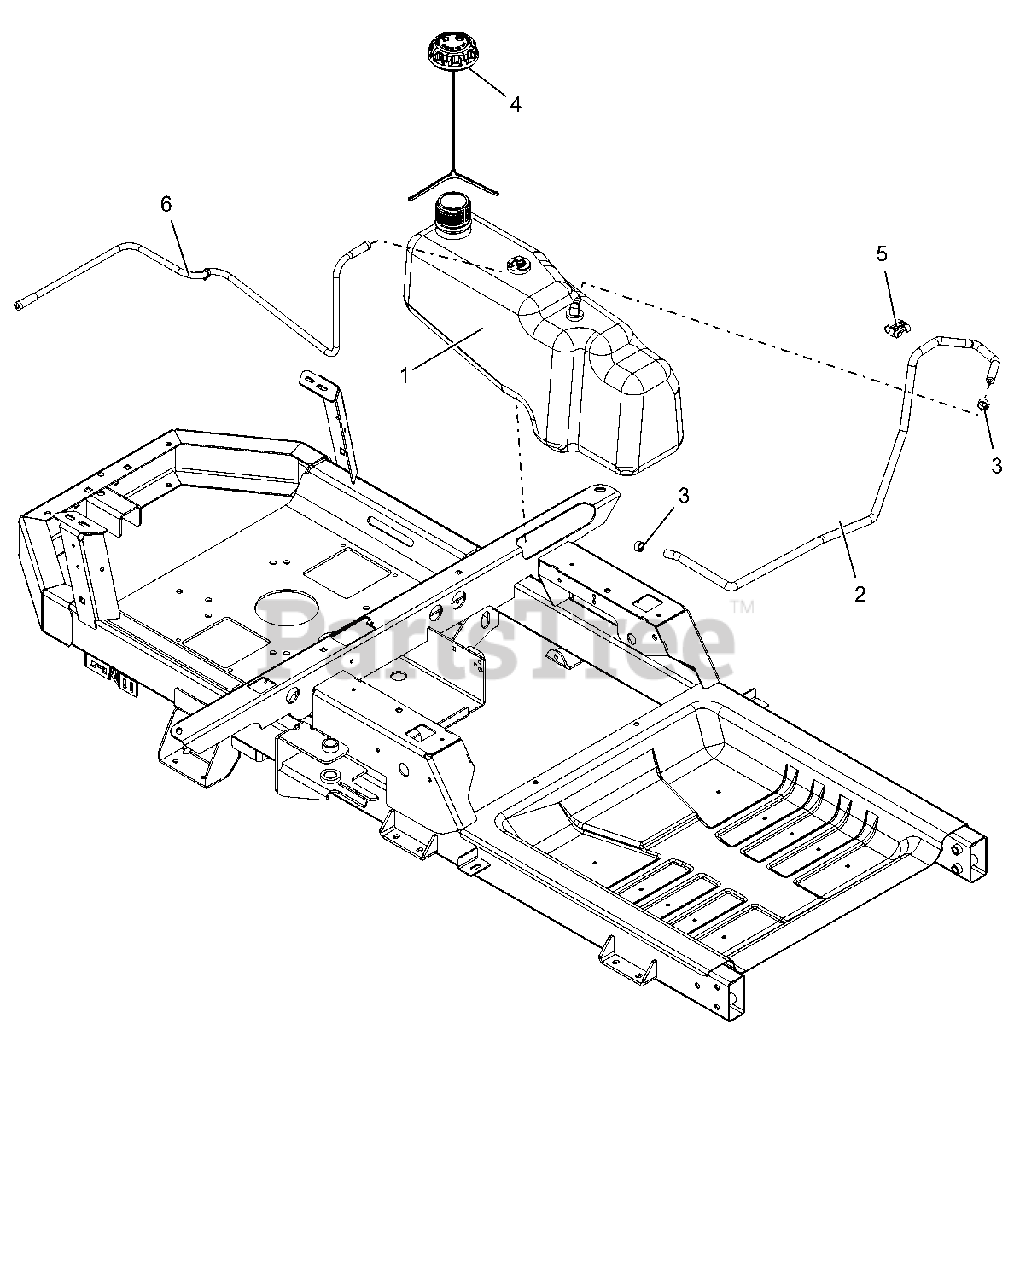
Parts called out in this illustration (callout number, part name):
1	ASM, TANK NON-PERM FUEL
2	HOSE, .25 LOW-PERM BULK GAS-35" LONG
3	CLAMP, FUEL LINE
4	CAP, FUEL VENT-IN 2.25" RATCHET
5	CLIP, T, .38-.50
6	LINE, FUEL VENT-SHORT
